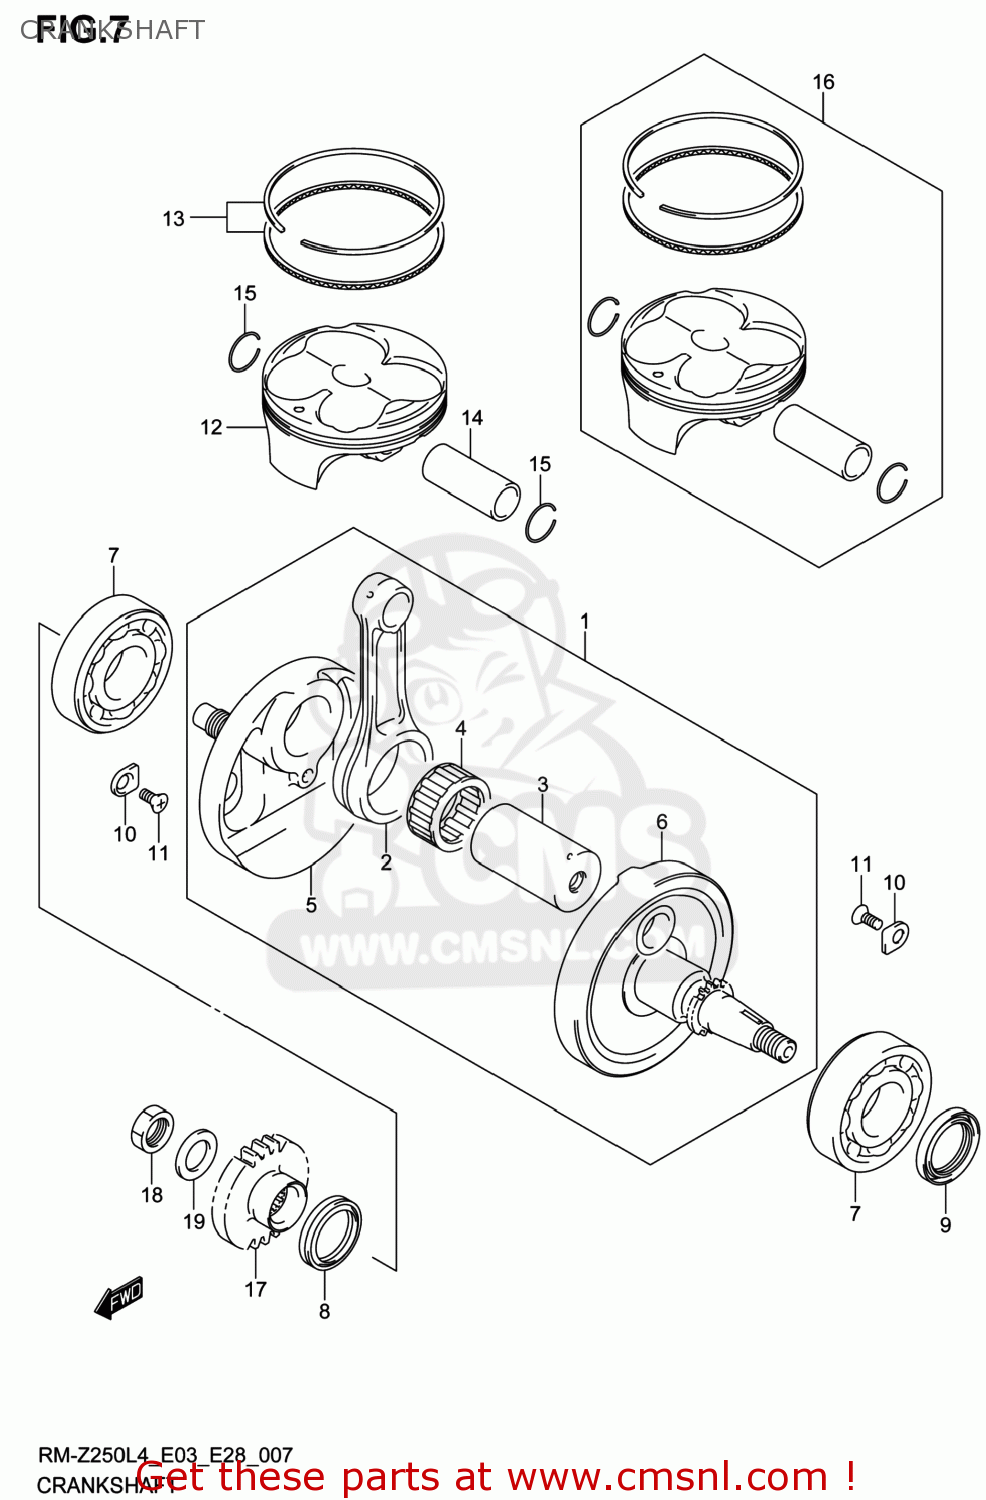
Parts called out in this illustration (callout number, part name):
1	CRANKSHAFT ASSY
2	CONNECTING ROD
3	PIN,CRANK
4	BEARING(30X38X18)
5	CRANKSHAFT,R
6	CRANKSHAFT,L
7	BEARING(30X63X16)
8	SEAL,OIL(30X40X7)
9	SEAL,OIL(30X40X6)
10	RETAINER,CRANKSHAFT BEARING
11	SCREW(6X12)
12	PISTON
13	RING SET,PISTON
14	PIN,PISTON
15	RING,SNAP 16MM
16	PISTON KIT
17	GEAR,PRIMARY DRIVE
18	NUT
19	WASHER
